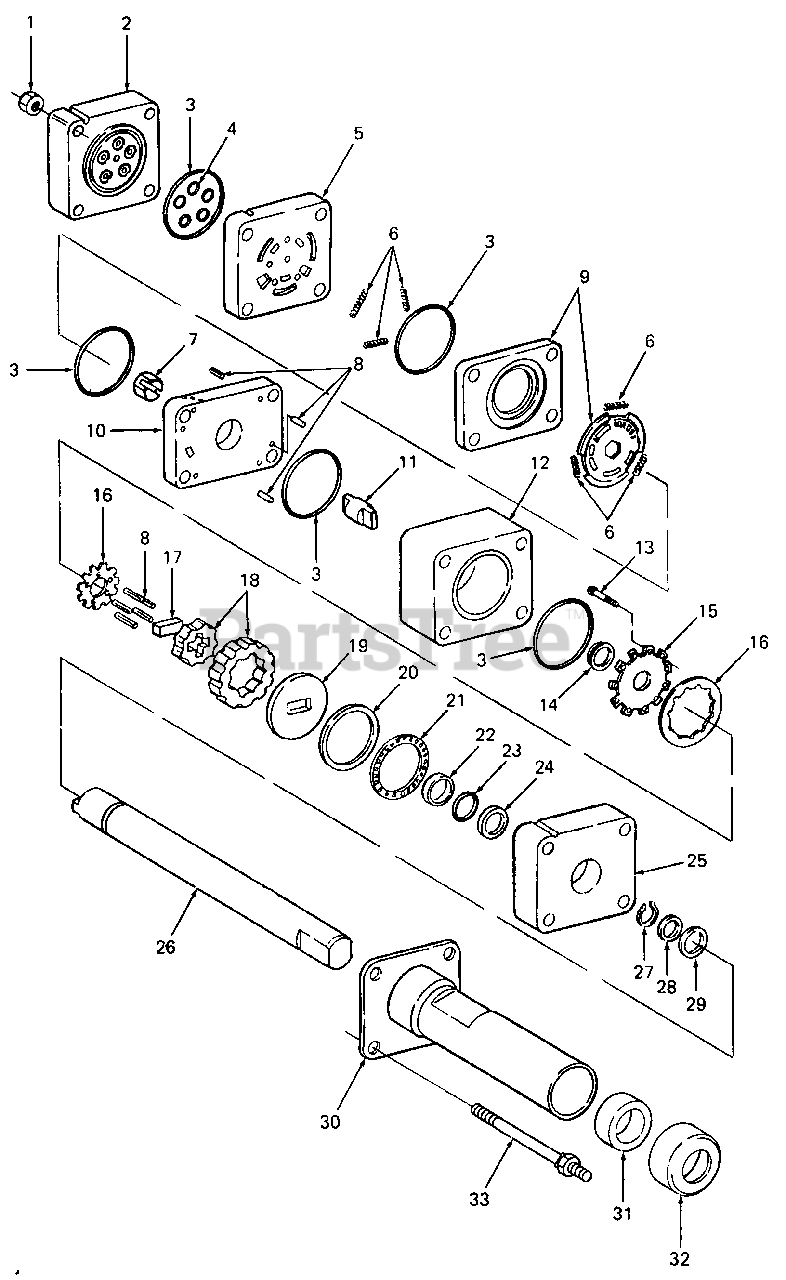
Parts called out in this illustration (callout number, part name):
1	Nut, Hex, 5/16-24
2	Power Cover & Check Valve Assy
3	Ring, Seal
5	Manifold, Port
7	Drive Assy, Hex
8	Roller Kit, Needle
9	Valve & Ring Assy
10	Manifold, Isolation
12	Ring, Metering
15	Cover, Commutator
16	Commutator & Ring Assy
17	Spacer, Drive Link
21	Bearing, Thrust
22	Seal, Face
23	Ring, Back-up
24	Seal, Spacer
25	Plate, Upper Cover
26	Input Shaft Assy
27	Ring, Retaining
29	Plate, Retaining
30	Upper Cover & Tube Assy w/Flat
31	Bearing, Column
32	Dust Seal, Column
33	Bolt, Special
